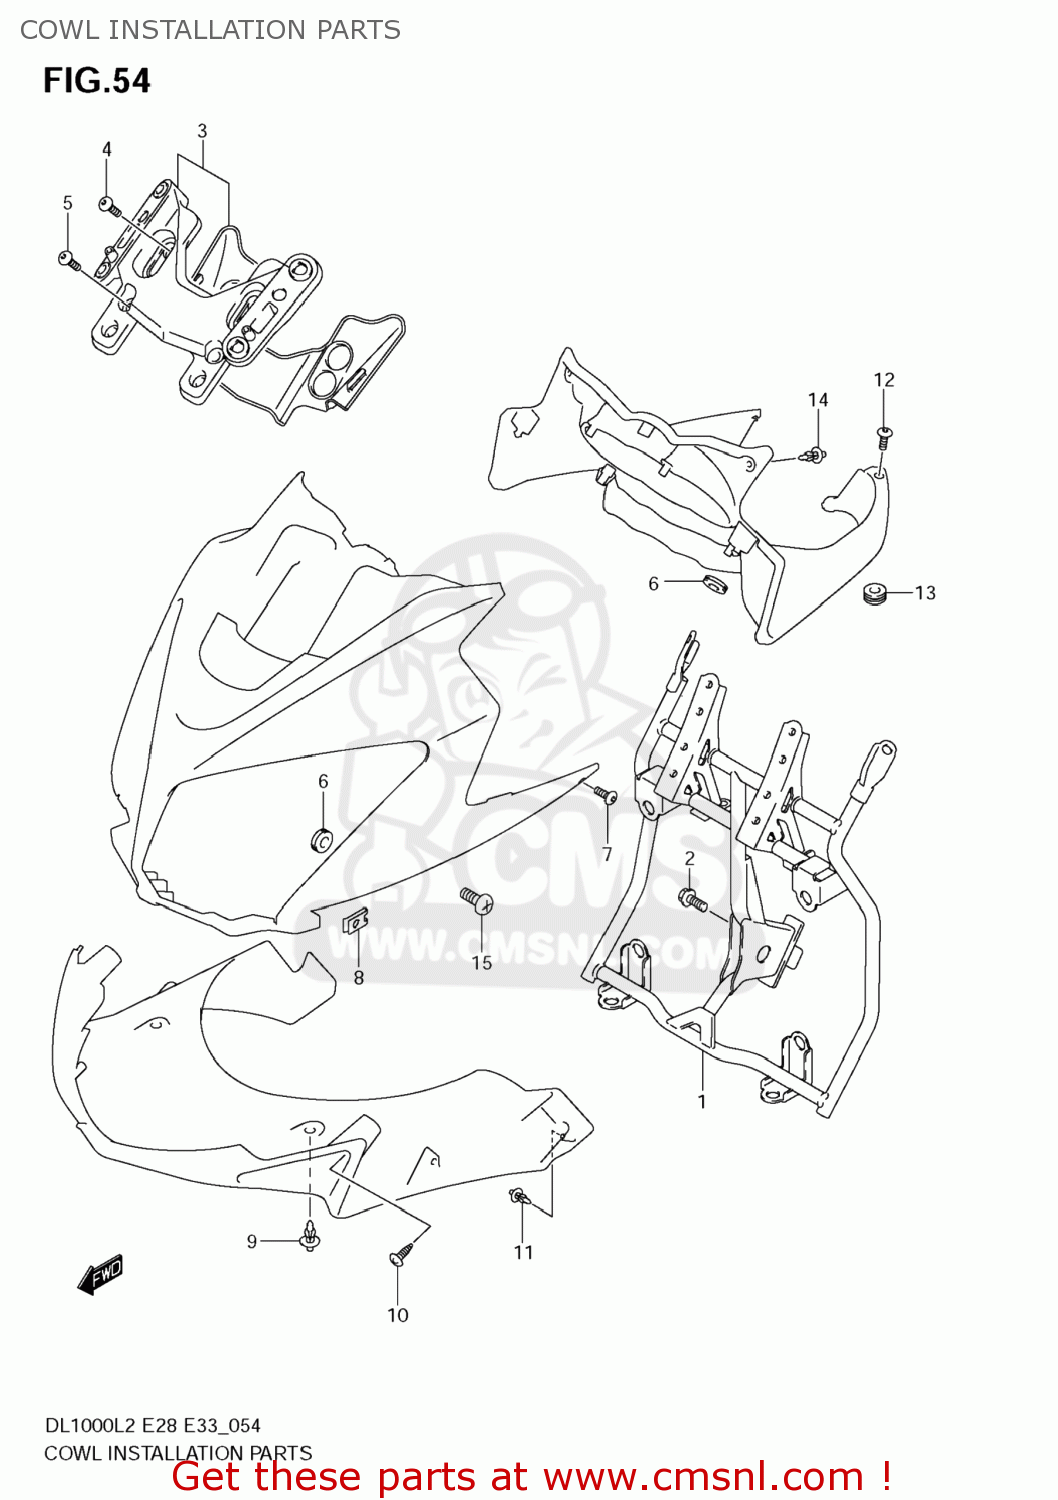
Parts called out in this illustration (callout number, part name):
1	BRACE,COWLING
2	BOLT
3	BRACE ASSY,WINDSCREEN
4	SCREW(6X20)
5	SCREW(6X16)
6	CUSHION
7	SCREW(5X13)
8	NUT
9	CLIP
10	SCREW
11	CLIP(BLACK)
12	SCREW(6X10)
13	CUSHION
14	CLIP(BLACK)
15	SCREW(5X16)
